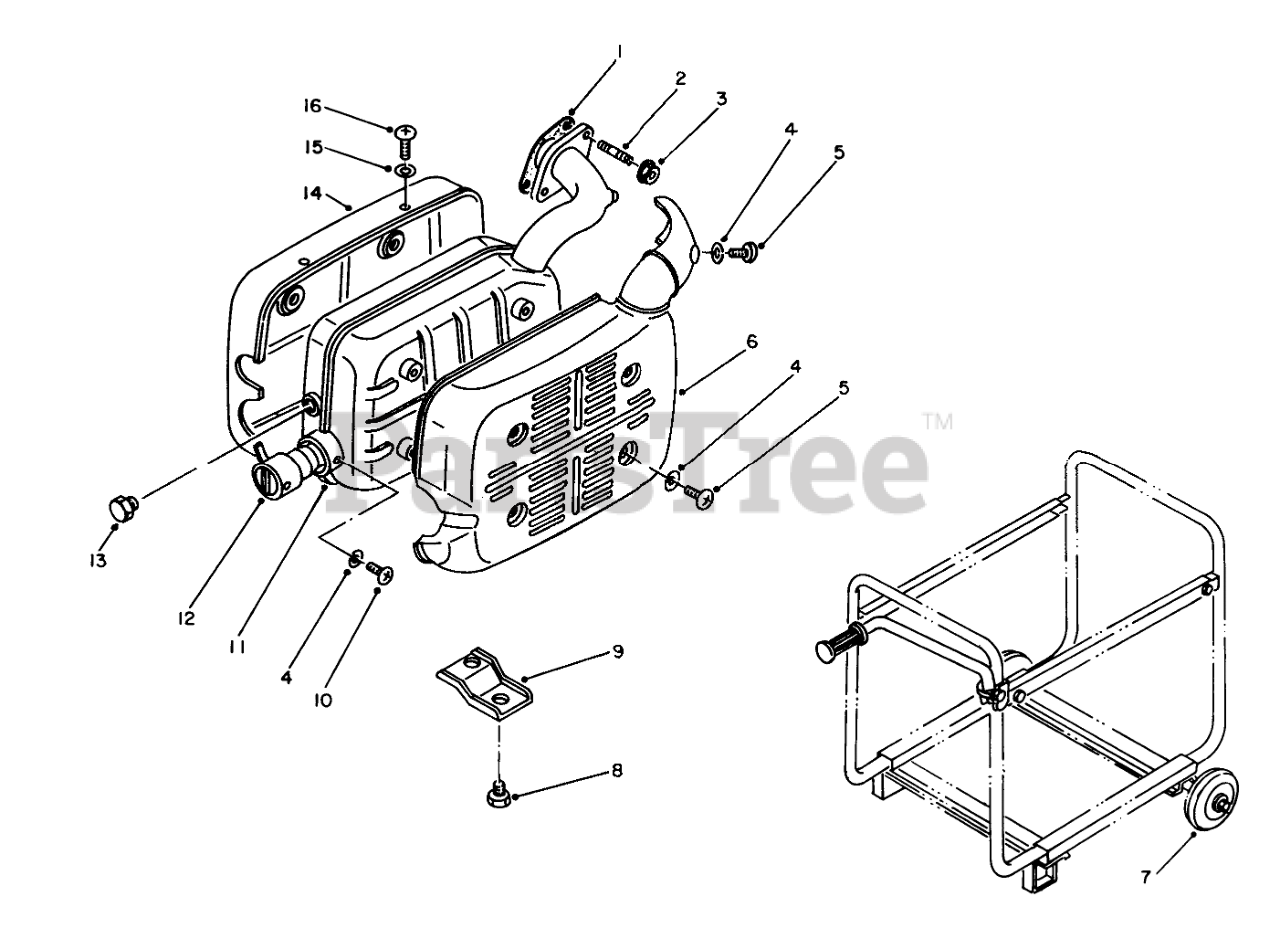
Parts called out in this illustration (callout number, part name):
1	Gasket-Exhaust
2	Stud Bolt
4	LOCKWASHER
5	SCREW
6	Cover-Front
7	Wheel Assembly (Optional)
9	Bracket
10	Screw
11	MUFFLER ASSM
12	Cleanout Tube
13	Drain Plug
14	Cover-Rear
15	Lockwasher
16	Screw
